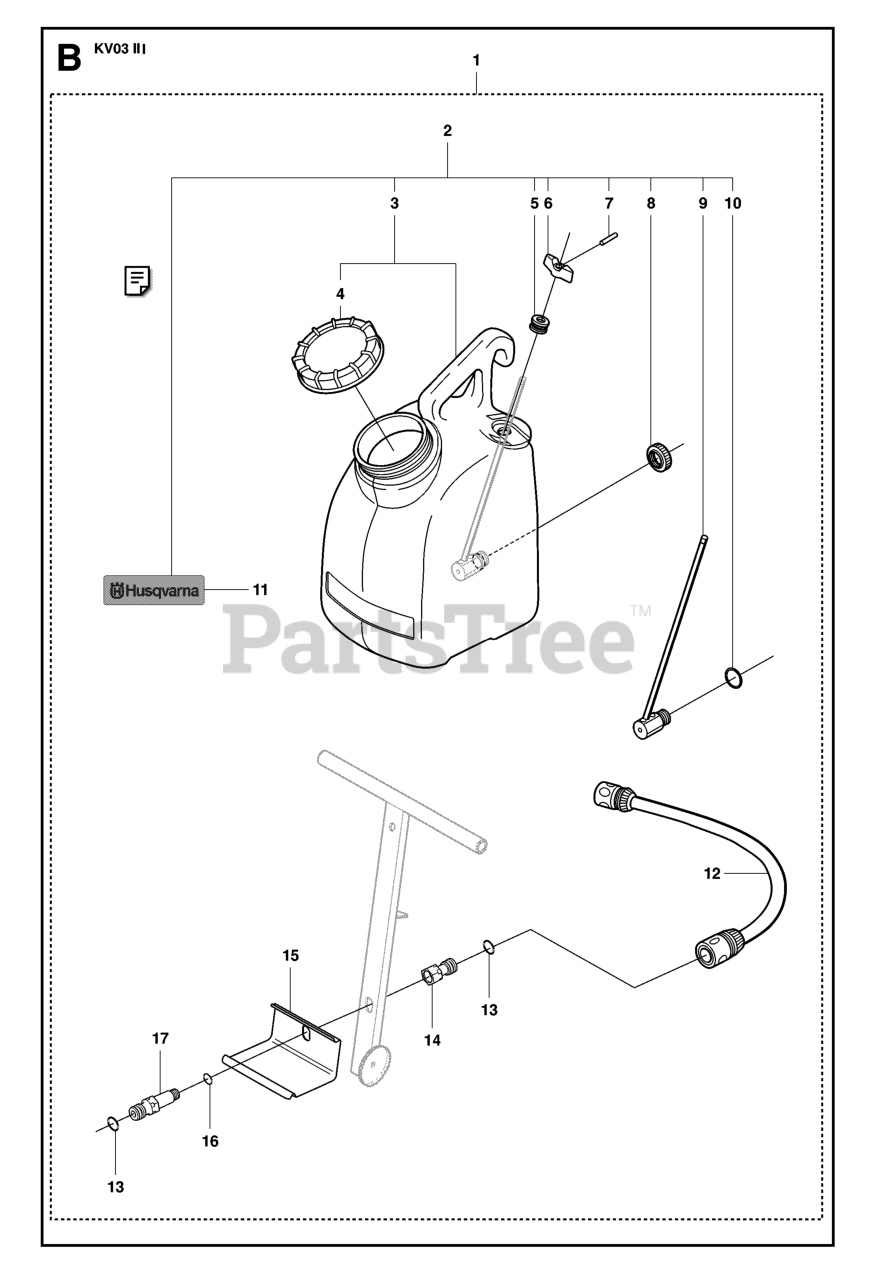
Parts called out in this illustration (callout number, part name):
1	WATER TANK CPL.
2	WATER TANK
5	ANTIVIBE ELEMENT
12	HOSE
